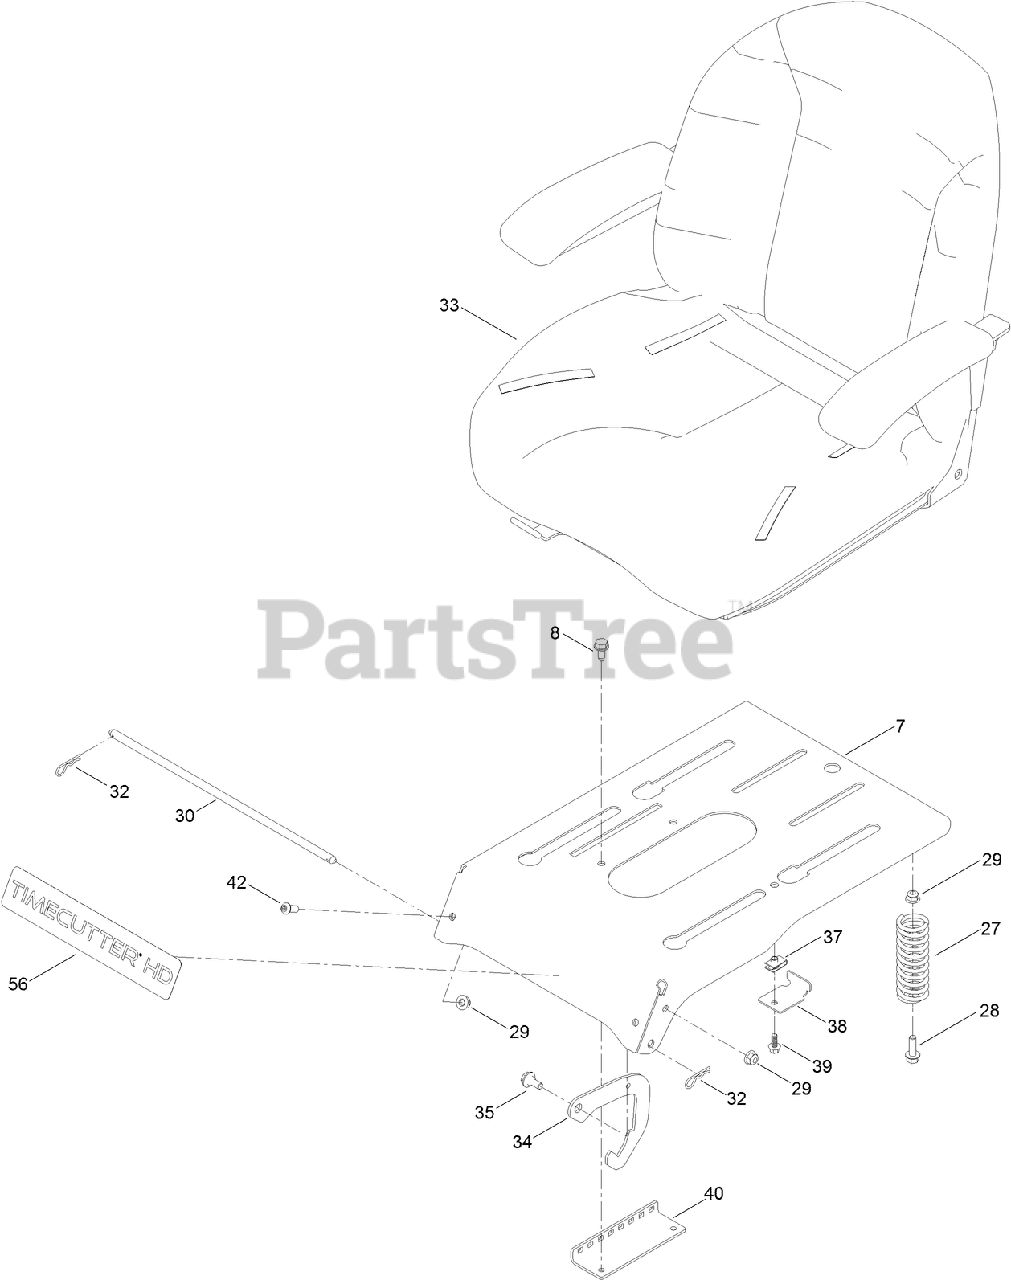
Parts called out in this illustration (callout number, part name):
7	PAN-SEAT, DELUXE
8	SCREW-HWHTF
27	SPRING-COMPRESSION
28	SCREW-HHF
29	NUT-HF, NI
30	ROD-PIVOT, NARROW
32	PIN-COTTER
33	SEAT ASM
34	LATCH-SEAT
35	SCREW-SHOULDER
38	BRACKET-STOP, SEAT
39	SCREW-HHF
40	BRACKET-LATCH, SEAT
42	SCREW-HSBH
56	DECAL-TIMECUTTER HD
